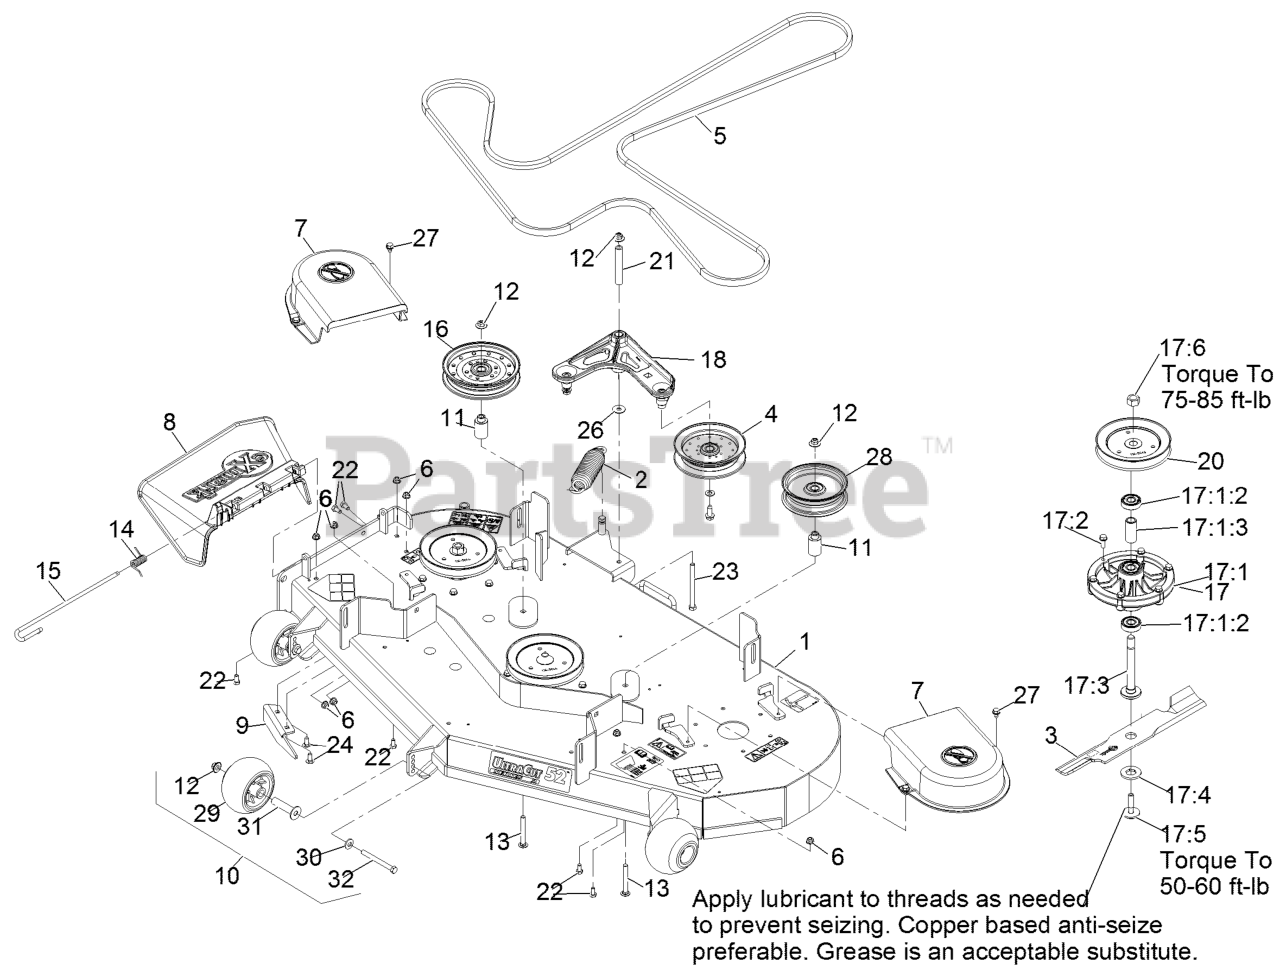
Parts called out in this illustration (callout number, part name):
1	ASM-522 DECK W/DECALS
2	SPRING-EXTENSION
5	BELT-B162.50
6	NUT-HF, NI
7	SHIELD-BELT
8	CHUTE DEFLECTOR XRK M056
9	BAFFLE-DISCHARGE
10	KIT, ANTI-SCALP ROLLER
11	BUSHING-IDLER
12	Nut-Nyloc 3/8-16 Flg
13	BOLT-CARRIAGE
14	SPRING-TORSION
15	PIN-CHUTE
17	CUTTER HOUSING ASM
17:1	HOUSING-CUTTER
17:1:2	BEARING
17:1:3	SPACER-BEARING
17:2	SCREW-TAPTITE
17:3	SPINDLE-HEX PILOT
17:4	WASHER-BLADE DRIVE
17:5	BOLT-BLADE, SEM
17:6	NUT-HEX
18	IDLER ARM ASM
20	SHEAVE,BLADE DRIVE 6.50
21	BUSHING
22	SCREW-HH
23	SCREW-HH
24	SCREW-CARR
28	IDLER-PULLEY, FLAT
29	ROLLER-SCALP, ANTI
30	WASHER-BELLEVILLE
31	AXLE, ROLLER
32	SCREW-HH 3/8-16 X 3 3/4 GR 8
